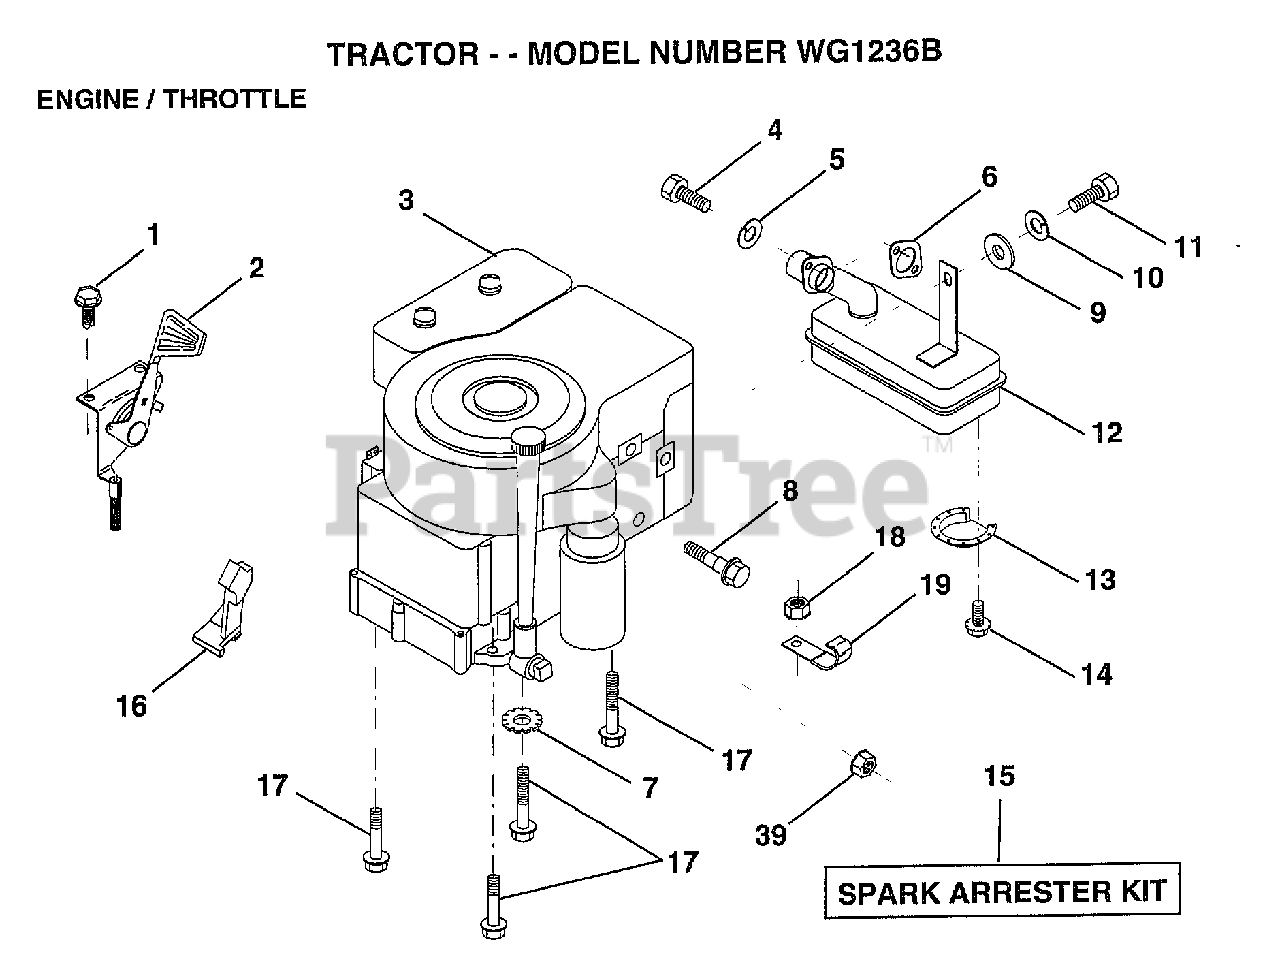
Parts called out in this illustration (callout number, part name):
1	SCREW.1/4-20X1/2
4	SCREW
5	LOCKWASHER
7	LOCKWASHER
8	BOLT T
10	LOCKWASHER
11	BOLT
12	MUFFLER
13	DEFLECTOR.222573
16	"STOP,DASH THROTT"
17	SCREW LT
18	NUT
19	CLIP T
39	NUT
